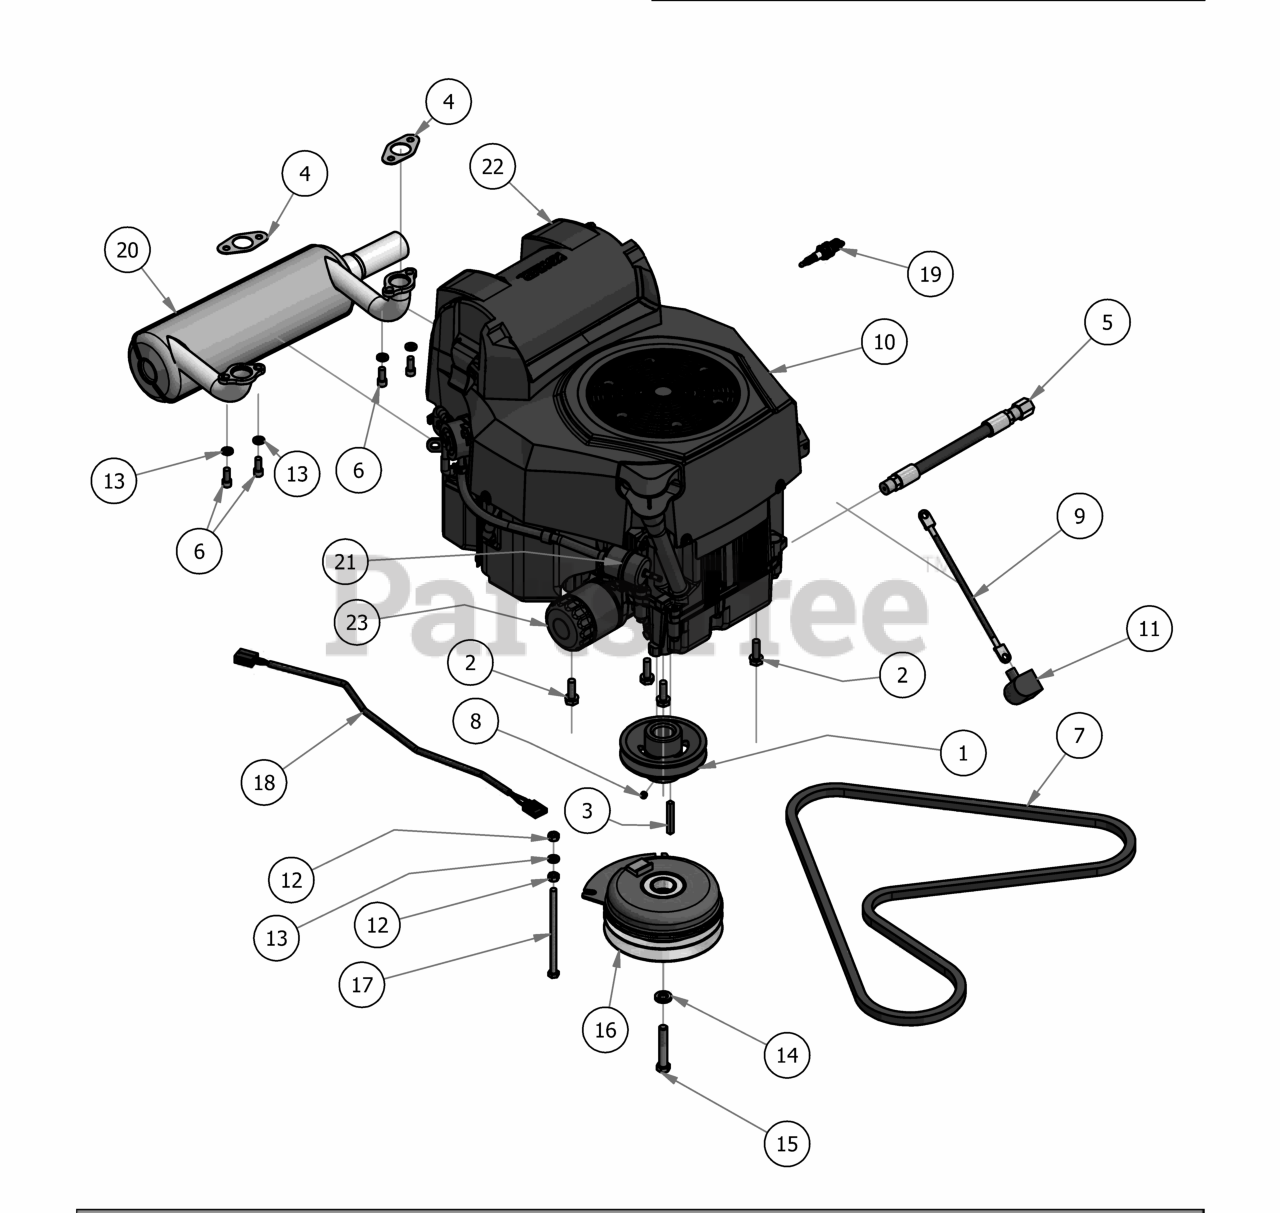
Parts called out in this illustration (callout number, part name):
1	4 3/4 Motor Pulley
2	3/8 x 1 1/8 bolt
3	1/4 x 2 Square key Stock
4	Exhaust Gasket
5	Oil drain Valve
6	5/16-18 x 3/4 Socket C/S
7	75.8 Pump Belt
8	5/16 Set Screw
9	Ground Cable
10	Kohler 747cc Engine
11	Black Boot For Ground Cable
13	5/16" Lock Washer
14	7/16" Lock Washer
15	7/16" x 2 1/2" Hex Bolt
16	Clutch Assembly
17	5/16-18 x 5-1/2 GR 5 Hex Bolt
18	Clutch Pigtail
19	Spark Plug
20	Kohler Muffler
21	Universal Inline Fuel Filter
22	725 Kohler air filter
23	725 & 747 Kohler Oil Filter
